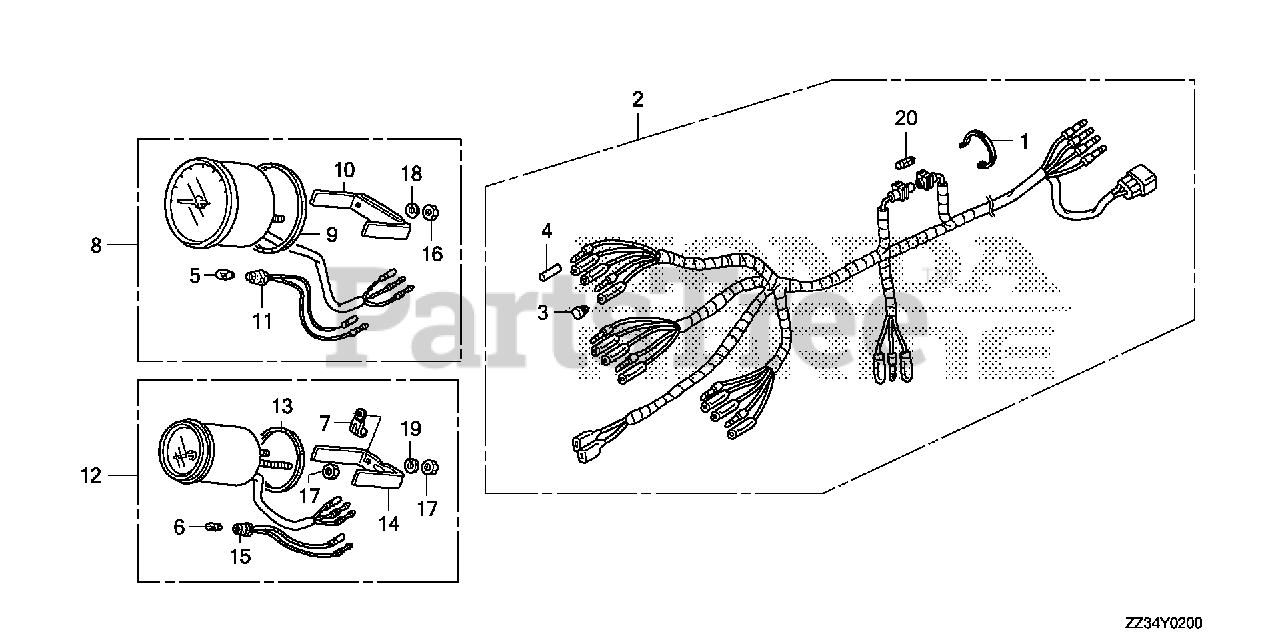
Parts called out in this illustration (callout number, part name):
1	BAND B1, WIRE
2	HARNESS ASSY., METER (A)
3	PLUG, CONNECTOR (INNER)
4	PLUG, CONNECTOR (OUTER)
5	BULB, WEDGE BASE (T10) (12V 1.7W) (STANLEY)
6	BULB, WEDGE BASE (12V 1.7W)
7	CLAMP
8	TACHOMETER ASSY.
9	GASKET
10	BRACKET
11	SOCKET
12	METER ASSY., TRIM
13	GASKET
14	BRACKET
15	SOCKET
16	NUT, HEX. (5MM)
17	NUT, HEX. (4MM)
18	WASHER, SPRING (5MM)
19	WASHER, SPRING (4MM)
20	FUSE A (10A)
